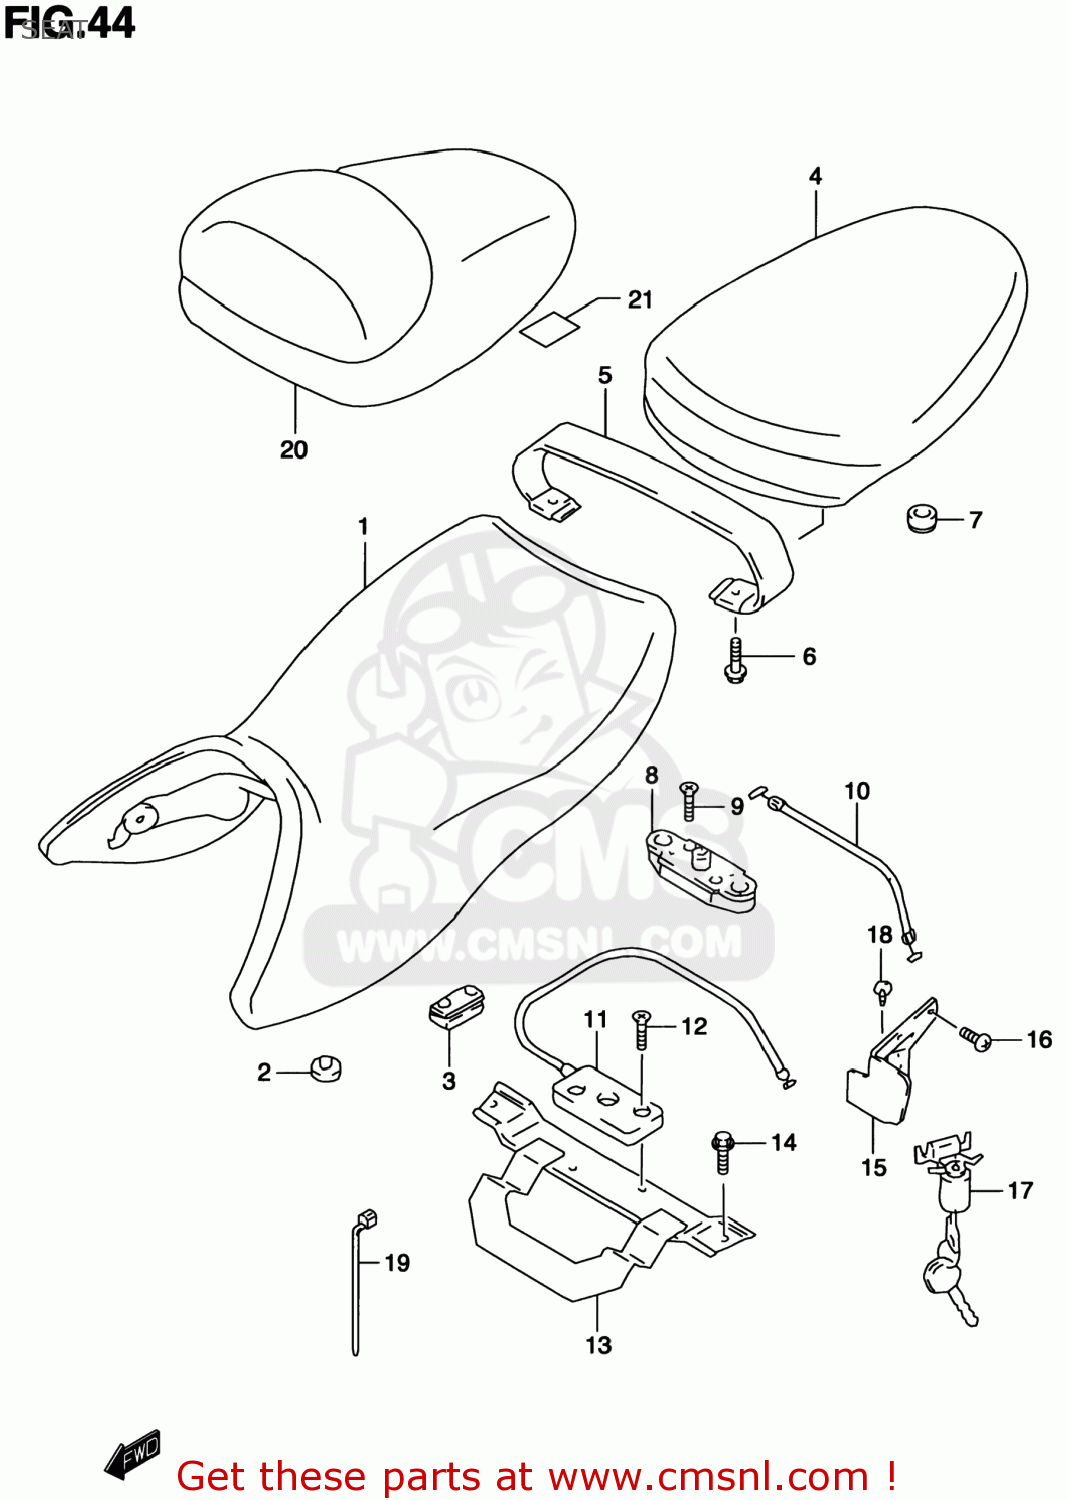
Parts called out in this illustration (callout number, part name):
1	SEAT ASSY(BLACK)
2	CUSHION,SEAT
3	CUSHION,SEAT(40X20X15)
4	SEAT ASSY,PILLION(BLACK)
5	BAND ASSEMBLY,PILLION SEAT
6	BOLT
7	CUSHION
8	BRACKET,SEAT SUPPORT,RIGHT
9	SCREW
10	CABLE,SEAT LOCK
11	BRACKET,SEAT SUPPORT FR
12	SCREW
13	BRACKET,SEAT LOCK
14	BOLT
15	BRACKET,SEAT LOCK KEY CYLINDER
16	SCREW 6X12
17	LOCK SET,SEAT
18	SCREW
19	CLAMP(L:125)
20	BOX COMP,SEAT TAIL
21	PROTECTOR SET,SEAT TAIL BOX
